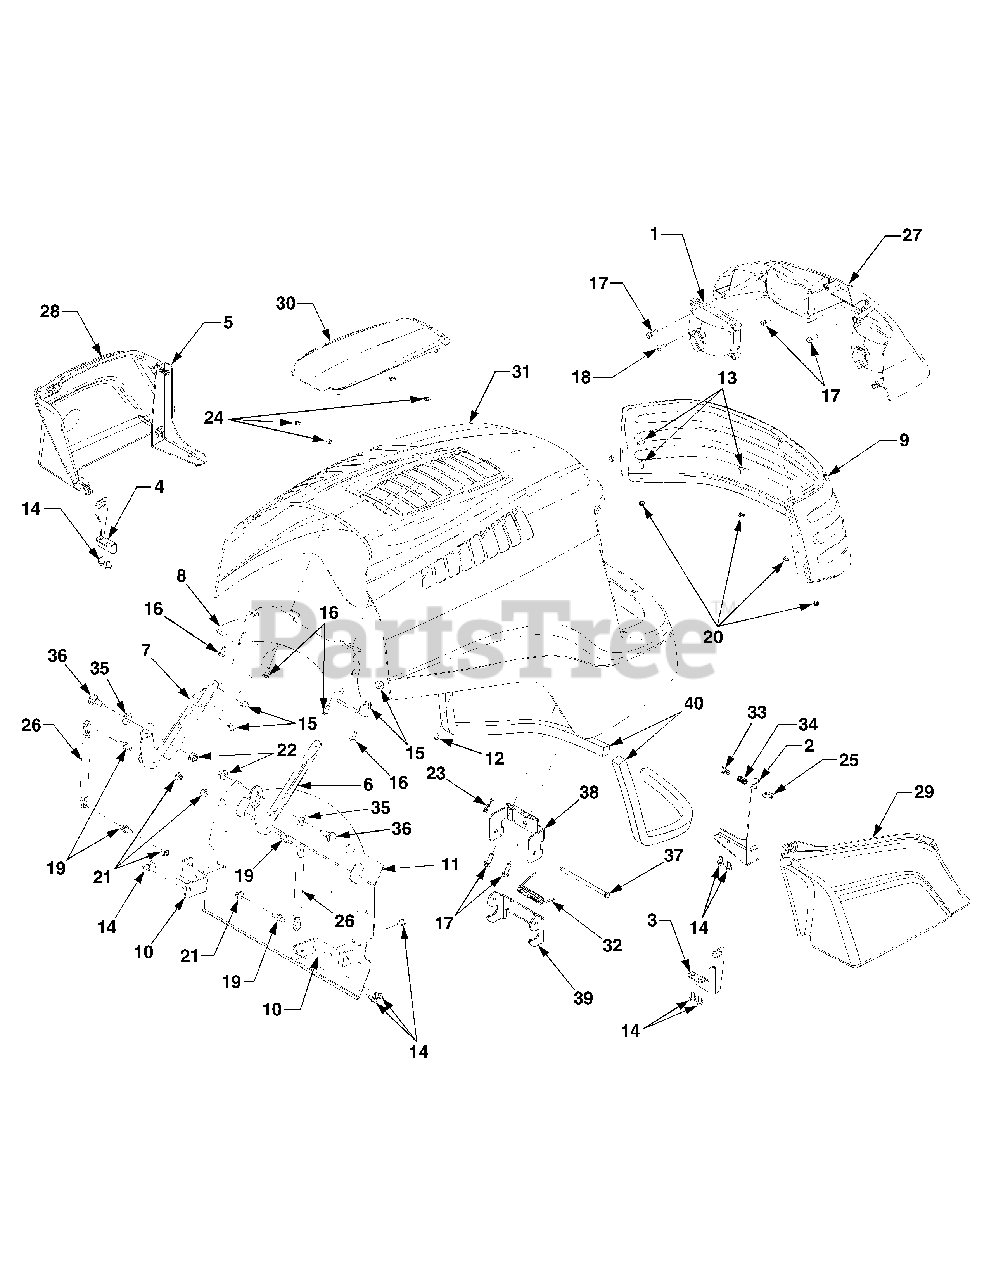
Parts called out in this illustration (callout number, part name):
1	Headlight Assembly
2	Brkt, Side Pnl. Mtg. RH
3	Brkt, Side Pnl. Mtg. RH Rear
4	Brkt, Side Pnl. Mtg. LH Rear
5	Brkt, Side Panel Mtg. LH
6	Bracket, Hinge, RH
7	Bracket, Hinge, LH
8	Bracket, Hood Mounting
11	Shield, Lower Heat
12	Screw, Hex Wash Hd, #8-18 x .375
13	Screw, Truss Hd, 10-24 x .5
14	Screw, Hex Wash Hd Tapp 1/4-20 x .5
15	Screw, Hex Wash Hd Tapp 5/16-18 x .5
16	Screw, Hex Cap 1/4-20 x .62 GR5
17	Screw, Hex Wash. Hd. 1/4-20 x .75
18	Screw, Truss Phil. Hd. 12-16 x .75
19	Stud, Cylinder, 5/16-18 Thrd
20	Nut, Hex Sems, 10-24
21	Nut, Hex Insert Flange Lock, 5/16-18
22	Nut, Hex Insert Flange Lock, 3/8-16
23	Pin, Internal Cotter
24	Nut, Push, .25 ID
25	Latch, 1/4 Turn Panel
26	Cylinder, Gas Spring
27	Bezel, Headlight
28	Panel, Side LH
29	Panel, Side RH
30	Cover, Hood
31	Hood Service Kit
31	Hood
32	Spring, Torsion
33	Clip, Spring
34	Spring, Compression
35	Washer, Flat, .51 x 1.0 x .060
36	Screw, Shoulder, .5 x .27 Lg 3/8-16
37	Rod, .25 x 4.55
38	Plate, Latch
39	Bracket, Latch Pivot
40	Seal, Foam, 3/4 x 3/4 x 20
